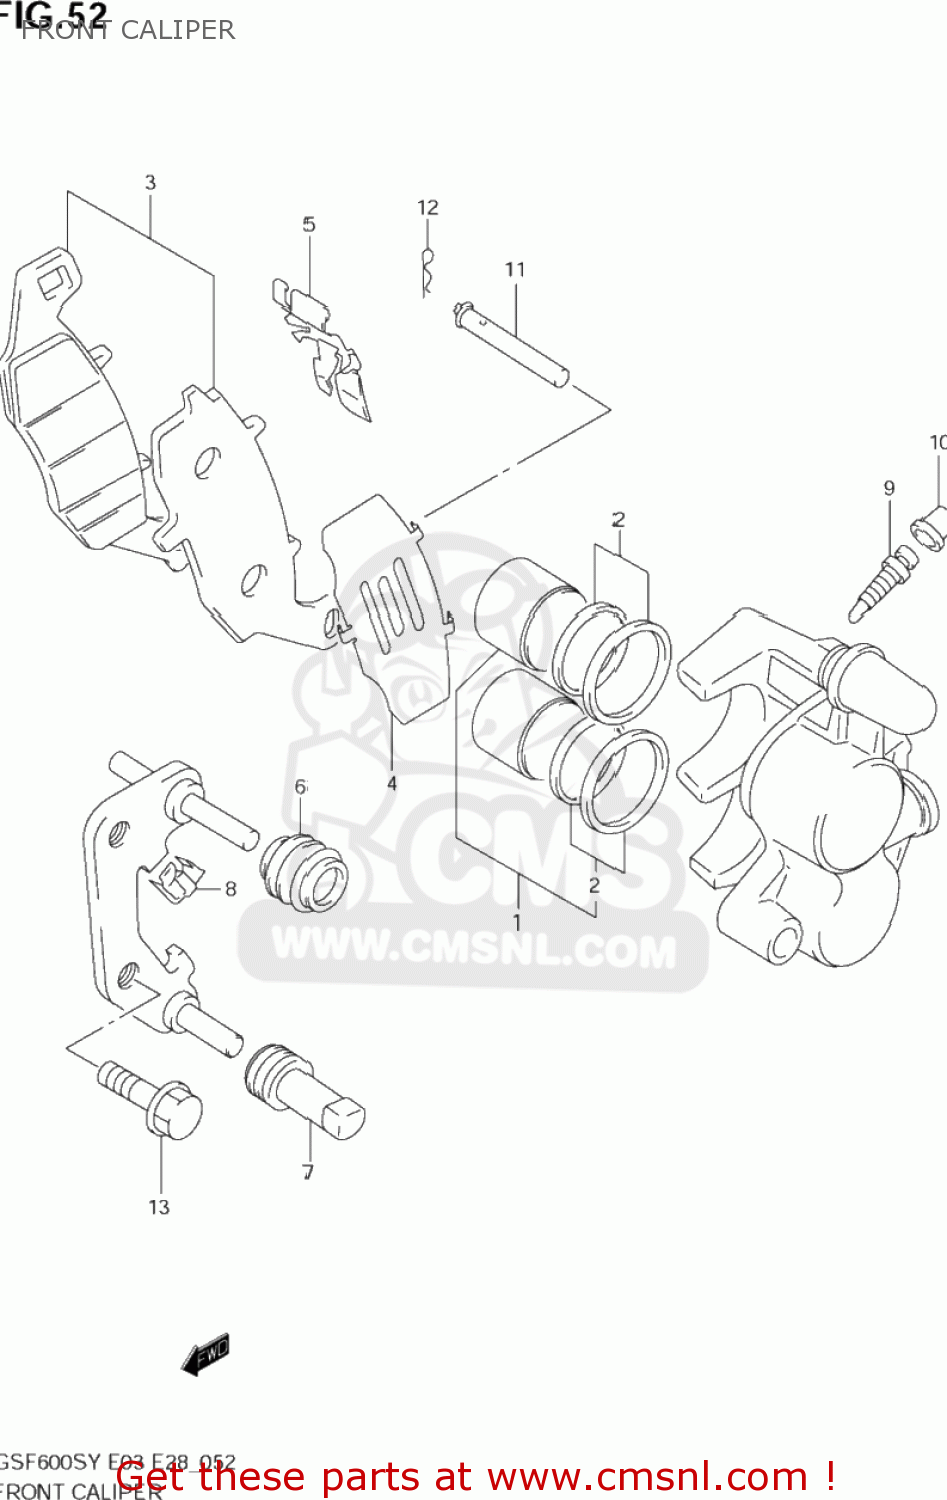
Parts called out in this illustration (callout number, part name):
1	PISTON SET
2	SEAL SET,PISTON
3	PAD SET,R (NAS)
4	SHIM,PAD
5	SPRING,PAD,R
6	BOOT,AXLE
7	INSULATOR,AXLE
8	GUIDE,PAD
9	BLEEDER
10	CAP,BLEEDER PLUG
11	PIN,PAD
12	CLIP,PAD PIN
13	BOLT
